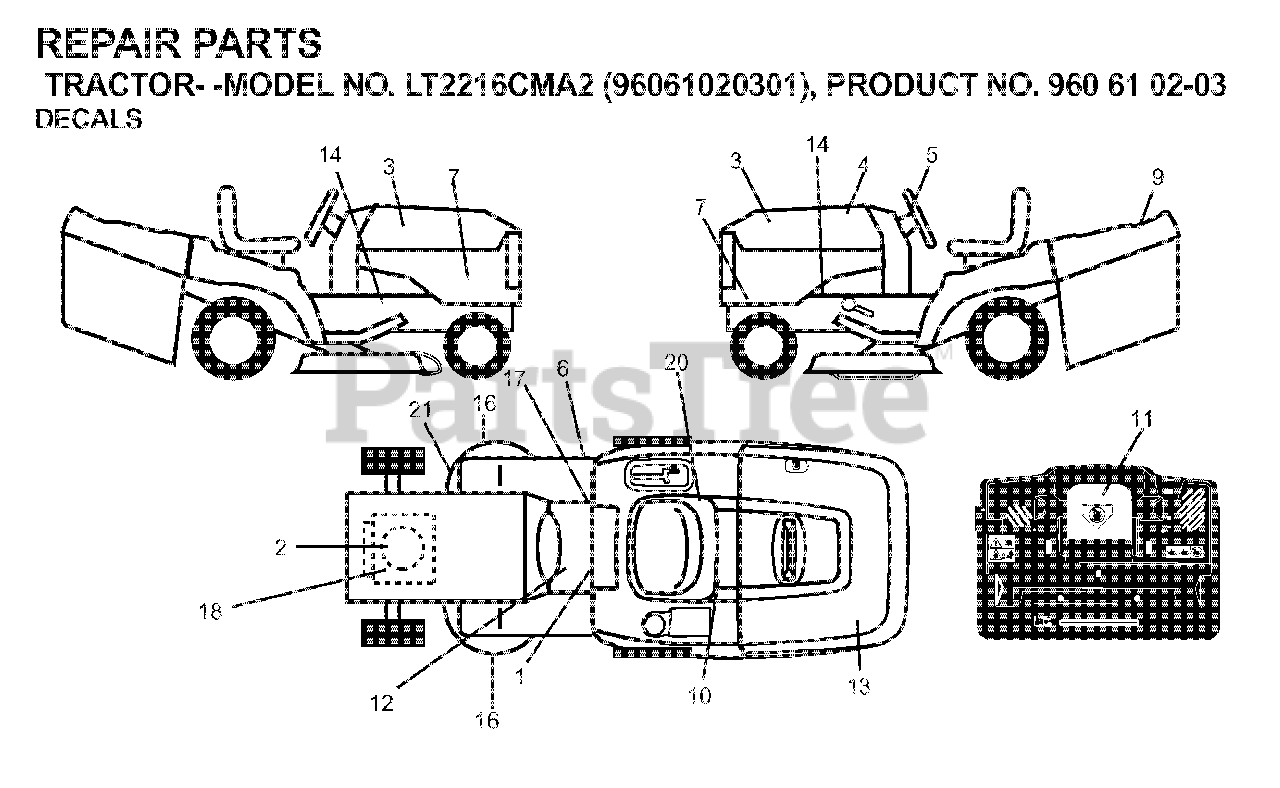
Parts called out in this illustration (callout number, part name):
10	DECAL BTRY SYMBOLS
11	DECAL.INTERNATIONL.CUTFINGER
17	DECAL PARK BRAKE
20	DECAL.BYPASS.FENDER.CRD.LT.YT
